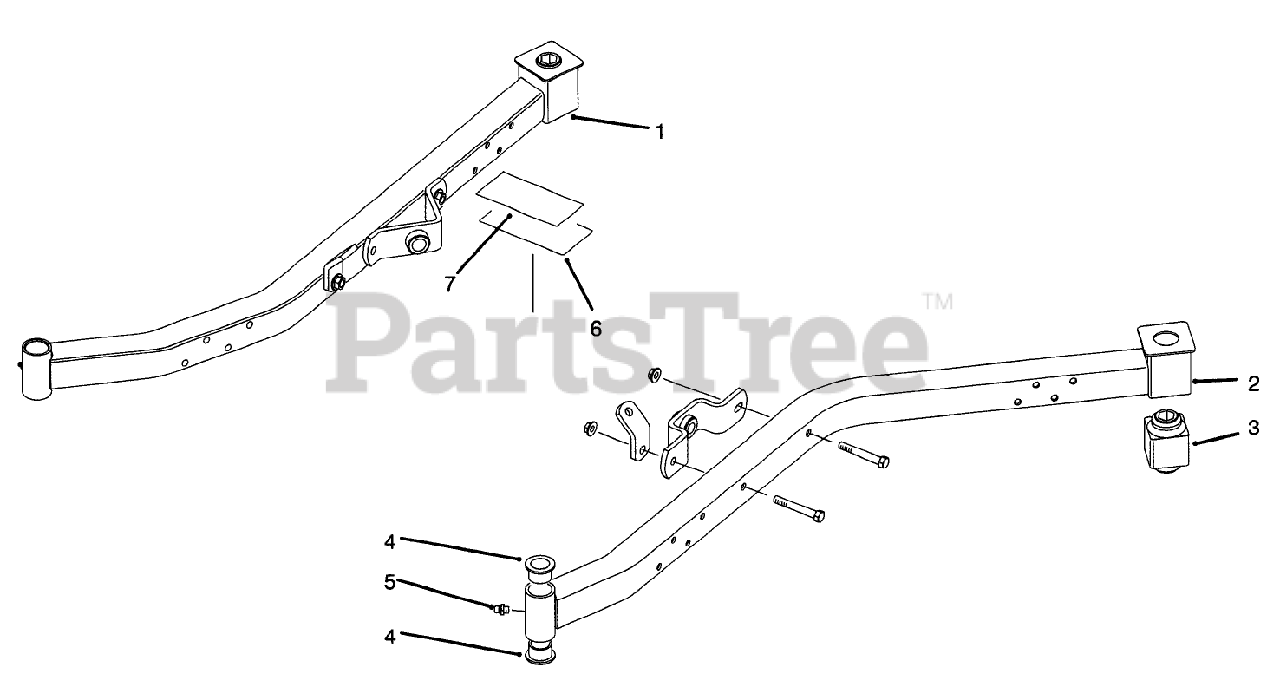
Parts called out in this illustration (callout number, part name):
1	Castor Arm Assembly RH (Incl. Ref. #3-5)
2	Caster Arm Assembly LH (Incl. Ref. #3-5)
3	BUSHING-RUBBER, SQUARE
4	BUSHING
5	FITTING-GREASE
6	DECAL-HOC
7	DECAL-HEIGHT OF CUT
